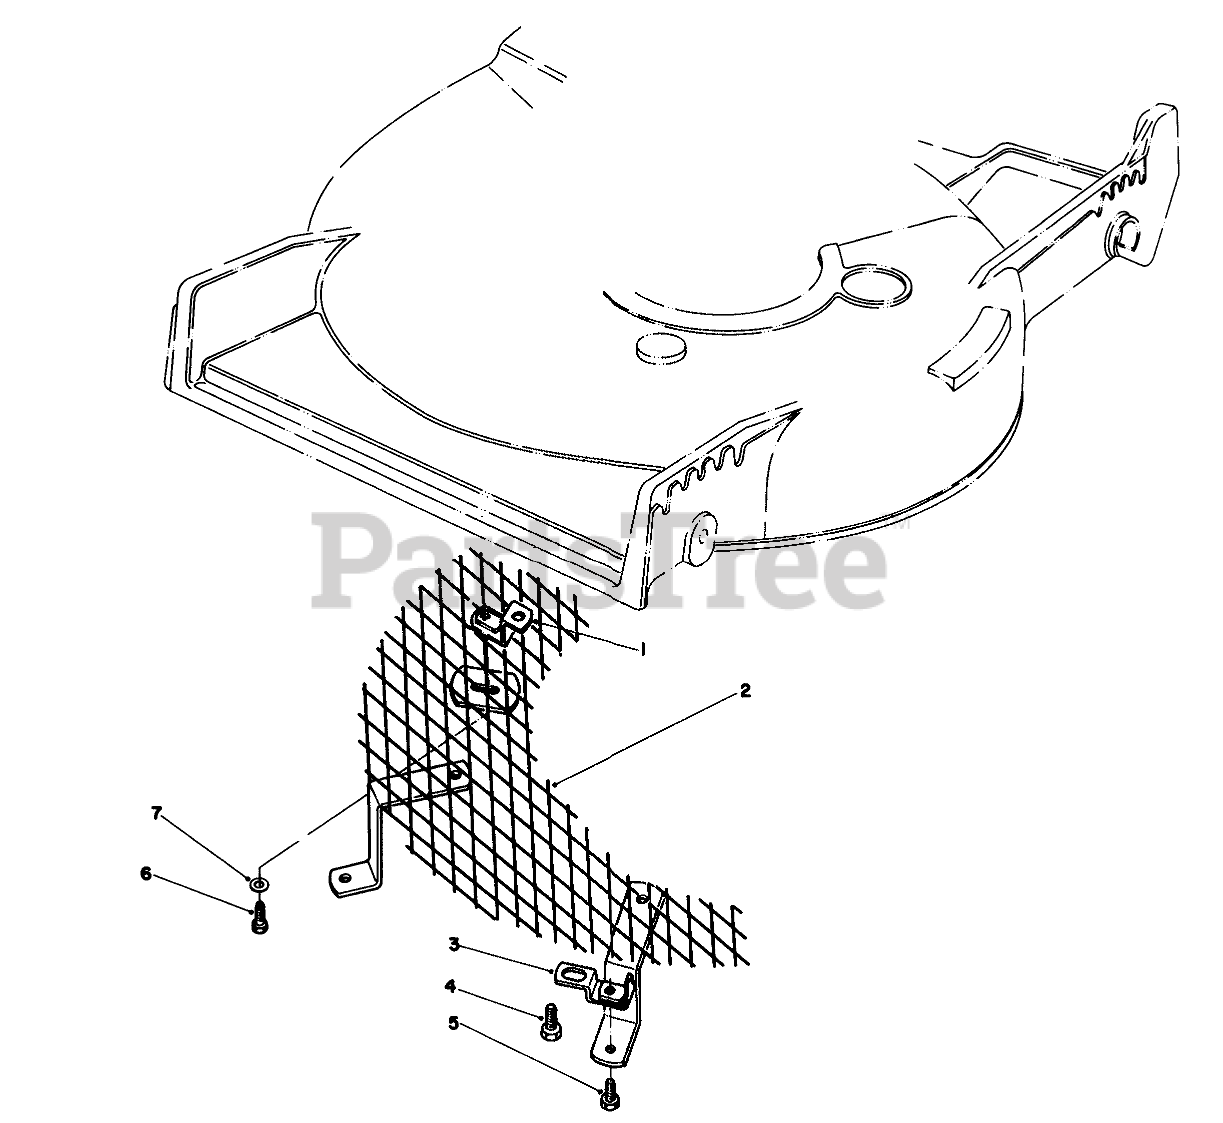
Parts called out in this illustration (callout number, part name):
1	BRACKET WA
2	SCREEN WA
3	Mounting Bracket
4	SCREW-HWHTF
5	SCREW-HH
6	SCREW-HH
7	WASHER-FLAT
